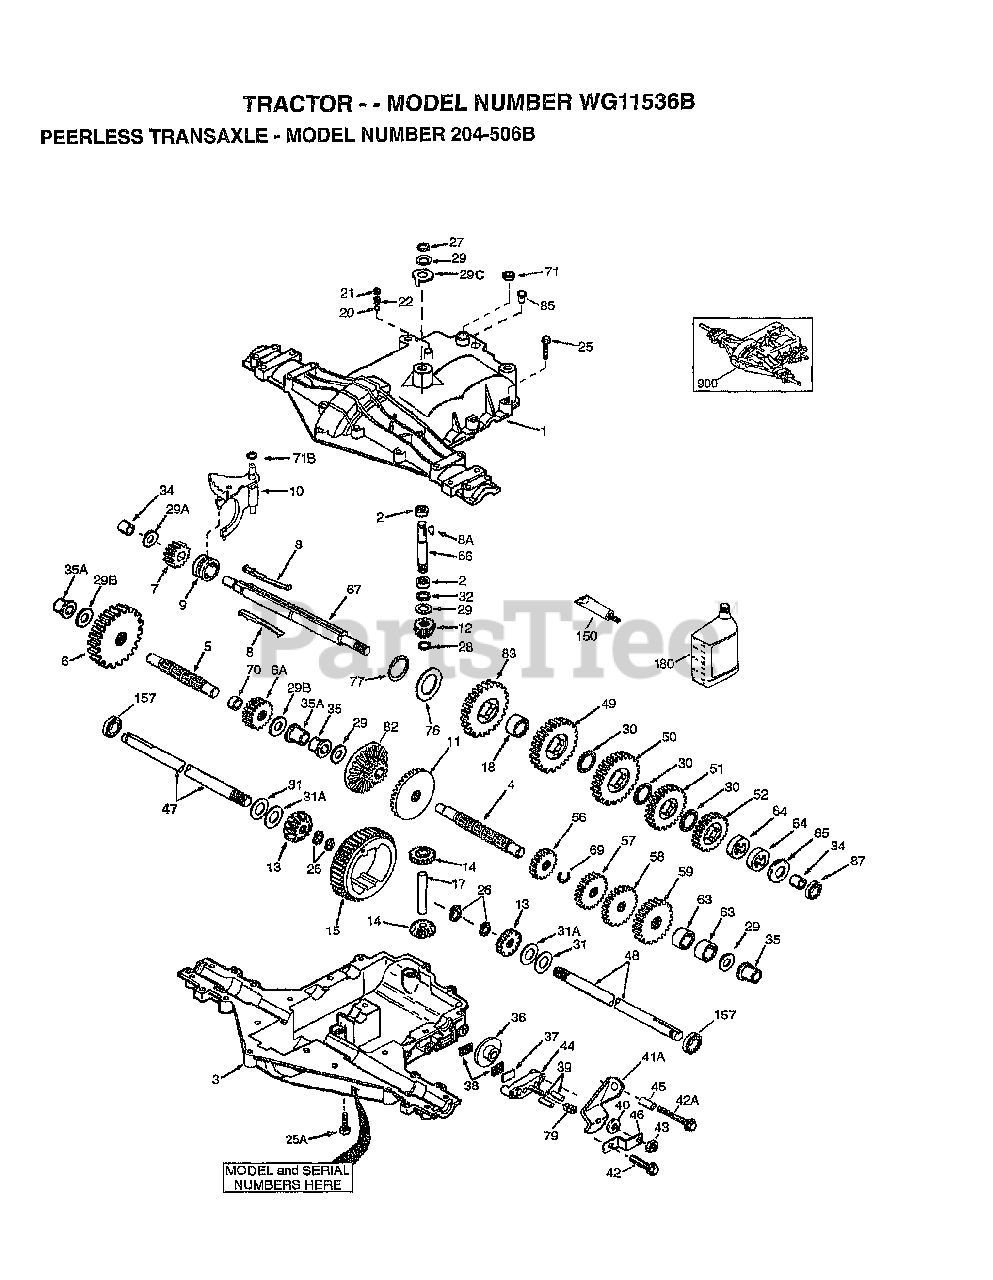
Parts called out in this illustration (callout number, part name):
1	TRANSAXLE COVER
2	NEEDLE BEARING 5/8" ID
3	TRANSAXLE CASE
4	COUNTERSHAFT
5	OUTPUT SHAFT
6	SPUR GEAR (38 TEETH)
6A	SPUR GEAR (15 TEETH)
7	SPUR GEAR (11 TEETH)
8A	KEY, WOODRUFF
9	COLLAR, SHIFTER
10	SHIFT ROD & FORK
11	BEVEL GEAR (30 TEETH)
12	INPUT BEVEL PINION (13TEETH)
13	BEVEL GEAR (13 TEETH)
14	BEVEL PINION (13 TEETH)
15	RING GEAR (43 TEETH)
18	SPACER, NEUTRAL
20	BALL STEEL, 5/16" DIA.
21	SCREW, 3/8-16 X 3/8"
25A	SCREW 1/4-20 X 1-3/8"
26	RING RETAINER
27	RING, RETAINER
28	RETAINING RING
29	WASHER THRUST
29B	WASHER THRUST
30	WASHER THRUST
31A	FLAT WASHER
32	OIL SEAL 5/8"
34	BUSHING 9/16"
35	FLANGED BUSHING 5/8" ID
35A	FLANGED BUSHING 3/4"
37	PLATE BRAKE PAD
41A	BRAKE LEVER
42A	SCREW, 1/4-20 X 2-1/4
43	LOCKNUT 5/16-24
44	HOLDER BRAKE PAD
46	BRKT BRAKE LEVER
49	SPUR GEAR (29 TEETH)
50	SPUR GEAR (23 TEETH)
51	SPUR GEAR (19 TEETH)
52	SPUR GEAR (15 TEETH)
56	SPUR GEAR (11 TEETH)
57	SPUR GEAR (17 TEETH)
58	SPUR GEAR (21 TEETH)
59	SPUR GEAR (25 TEETH)
66	INPUT SHAFT
67	SHIFTER & BRAKE SHAFT
69	RETAINING RING
70	SPACER .890
71	SEAL SQUARE CUT
76	WASHER, THRUST
77	INVERTED RETAINING RING
82	BEVEL & SPUR GEAR (30 & 13 TEETH)
83	SPUR GEAR (27 TEETH)
85	OIL FILL PLUG
87	OIL SEAL 9/16"
150	LIQUID GASKET RTV SILICONE
157	OIL SEAL 3/4"
180	GEAR OIL 80W90
